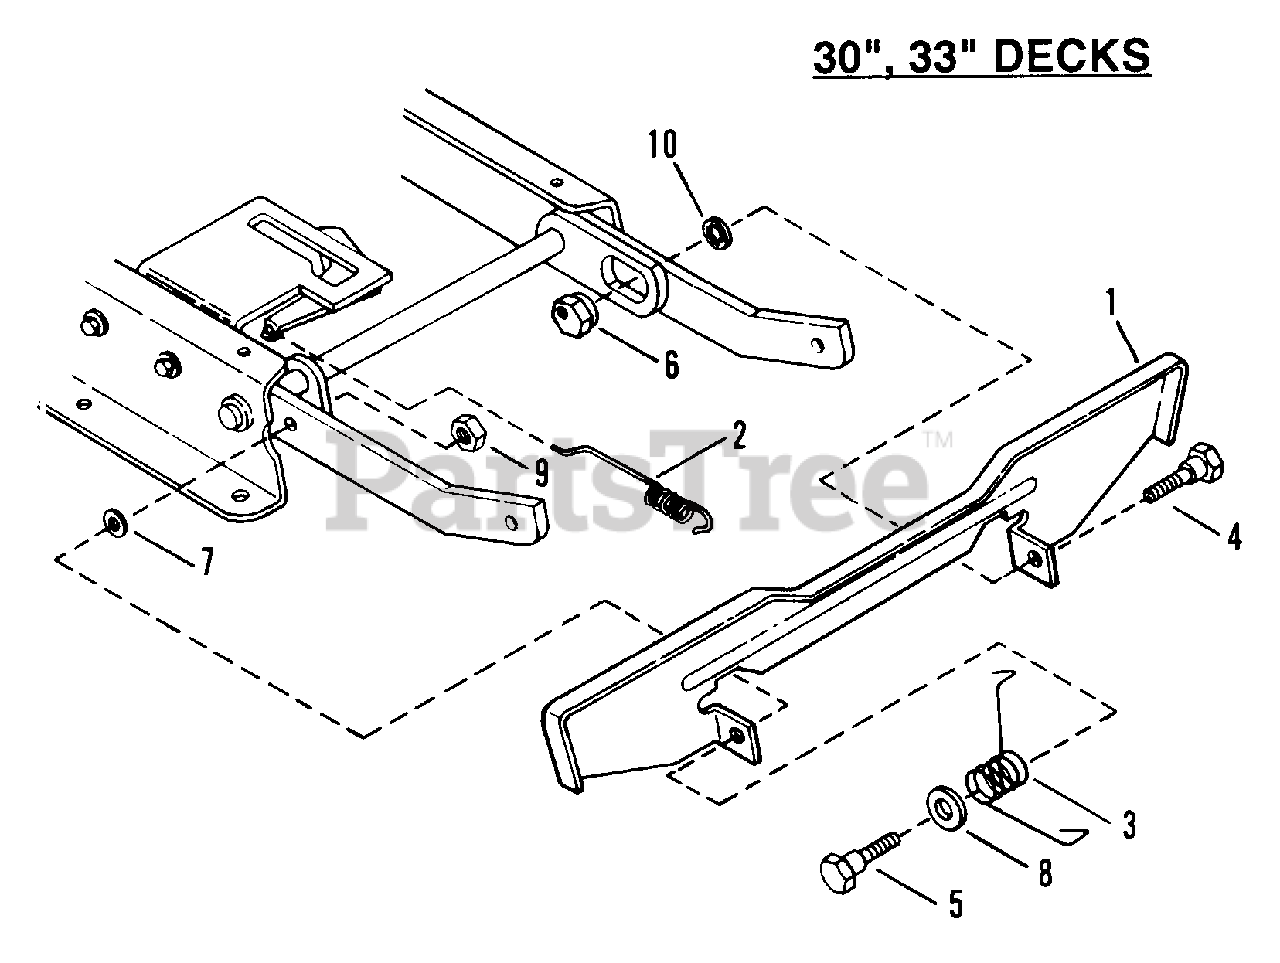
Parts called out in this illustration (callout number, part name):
1	PEDAL, Blade Stop Control
2	SPRING, Latching
3	SPRING, Pedal
4	BOLT, 3/8-24 x 3/4" Shoulder
5	BOLT, 3/8-24 x 9/16" Shoulder
6	ECCENTRIC, Leveling
7	WASHER, 3/8" Flat
8	WASHER, 1/2 Flat
9	NUT, 3/8-24 Hex Lock
10	WASHER, 3/8 Internal Tooth Lock
